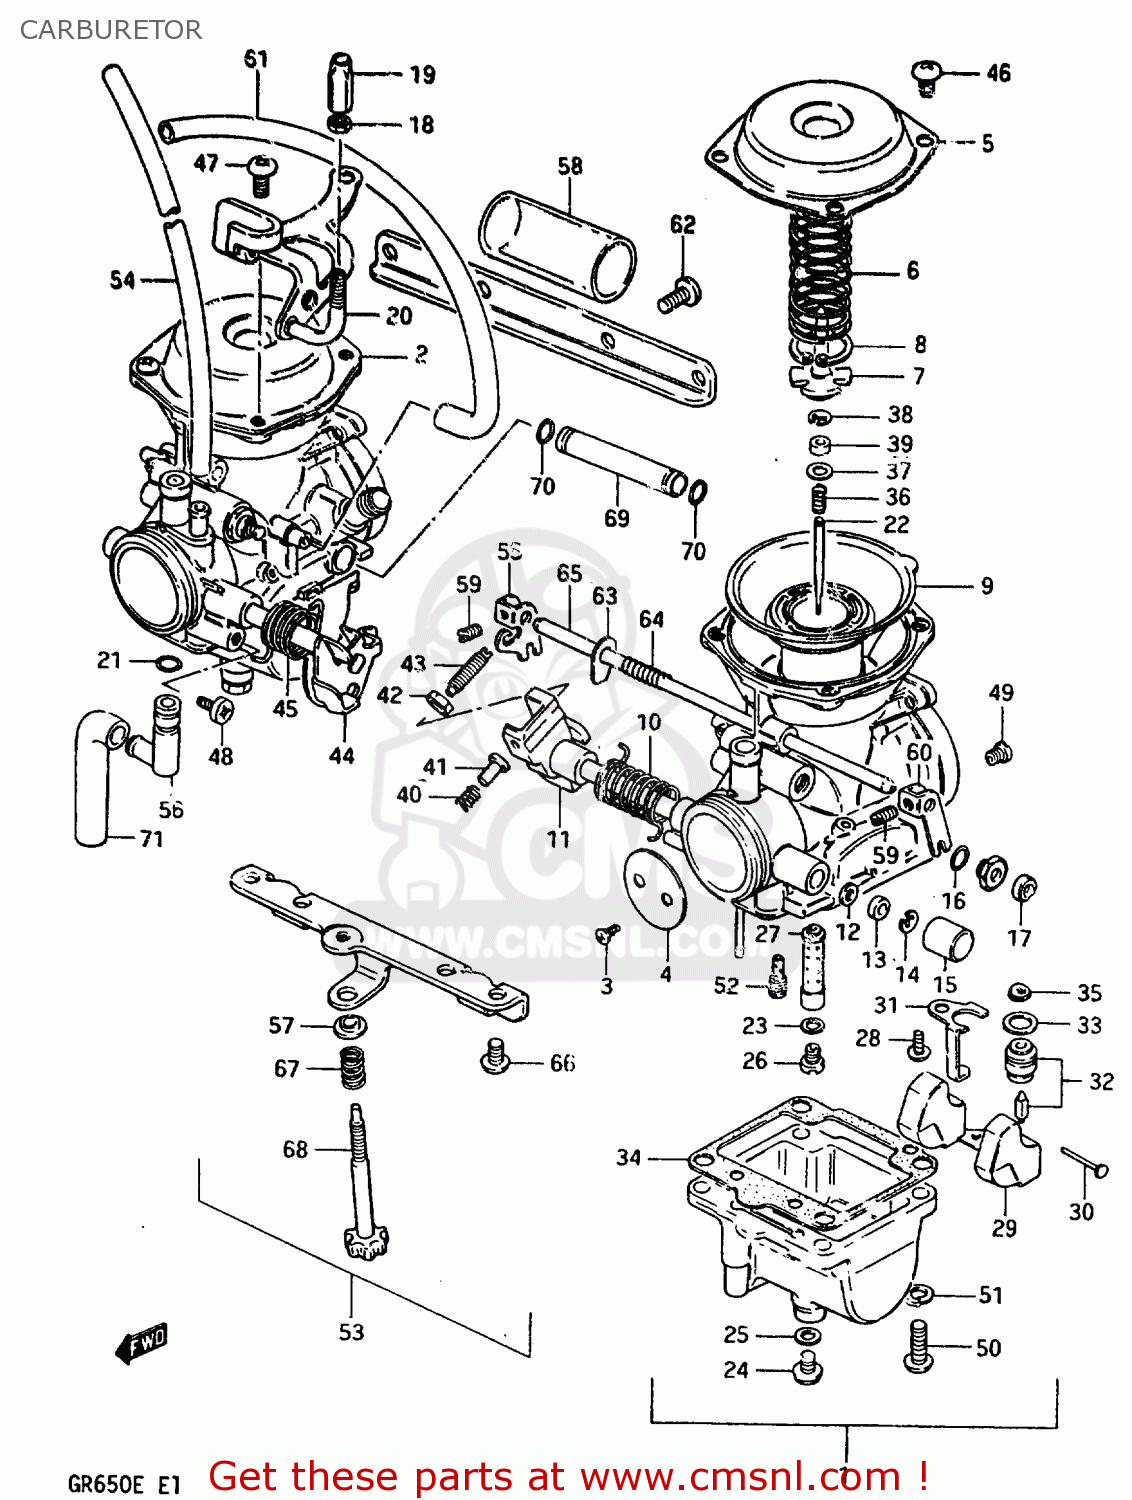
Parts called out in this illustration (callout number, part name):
1	CARBURETOR ASSY, LH
2	CARBURTOR ASSY, RH
3	SCREW
4	VALVE,THROTTLE (90)
5	COVER,DIAPHRAGM
6	SPRING,DIAPHRAGM
7	HOLDER,GUIDE
8	E RING
9	DIAPHRAGM,CARBURETOR
10	SPRING
11	SHAFT ASSEMBLY
12	SEAL
13	GASKET,THROTTLE SHAFT (NAS)
14	E RING
15	CAP
16	O RING
17	CAP,STARTER VALVE
18	NUT
19	ADJUSTER
20	BRACKET
21	O-RING
22	NEEDLE, JET (5C08-3)
23	WASHER,NEEDLE NOZZLE
24	PLUG,DRAIN
25	GASKET (NAS)
26	JET 130
27	JET, NEEDLE (Y-8)
28	SCREW 4X6
29	FLOAT
30	PIN,FLOAT
31	PLATE,NEEDLE VALVE FITING
32	VALVE ASSEMBLY,NEEDLE
33	O-RING,NEEDLE VALVE
34	GASKET,FLOAT CHAMBER (NAS)
35	FILTER
36	SPRING
37	WASHER
38	CLIP,NEEDLE
39	RING
40	SPRING,THROTTLE SCREW
41	PIN,THROTTLE LEVER
42	NUT
43	SCREW
44	SHAFT ASSEMBLY
45	SPRING
46	SCREW
47	SCREW
48	SCREW
49	JET
50	SCREW
51	LOCK WASHER
52	JET,PILOT(42.5)
53	CARBURETOR ASSEMBLY
54	HOSE
55	LEVER,STARTER
56	PIPE
57	RING,ADJUSTER
58	HOSE
59	SCREW,THROTTLE ADJUST
60	LEVER
61	HOSE
62	SCREW
63	WASHER,STARTER PLUNGER
64	SPRING,STARTER
65	SHAFT,STARTER
66	SCREW 6X12
67	THROTTLE SCREW
68	SCREW,THROTTLE STOP
69	PIPE,CARBURETOR
70	O RING
71	HOSE,CARBURETOR
